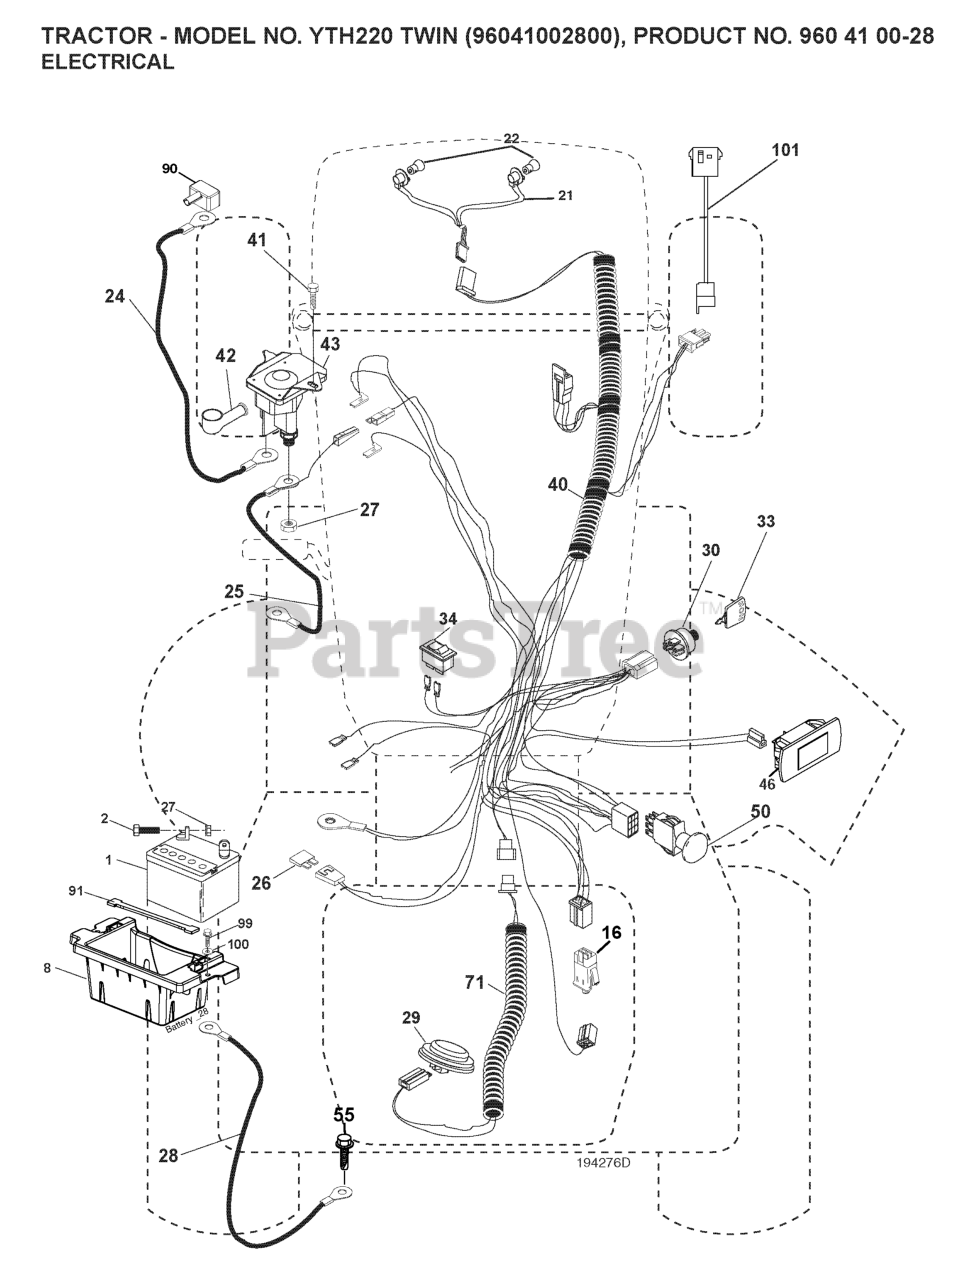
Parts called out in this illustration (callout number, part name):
1	BATTERY 12V .35 AMP
2	BOLT.HEX.1/4.X.3/4.DICHROMATE
8	BOX.BATTERY.MOUNT.FRONT.LT
16	SWITCH INTERLOOK PUSH-IN
21	HARNESS ASSY LIGHT
24	CABLE.BATT.POS.WIRE.TG.DA SOL
25	CABLE.START.RED.17.5".
26	FUSE 20AMP
27	NUT
28	CABLE GROUND 6 GA 21" 90T BLK
29	SWITCH.SEAT.DELTA.OPC.
30	SWITCH.IGN.DELTA.W.LGH.ROS
33	KEY MLD GEN DELTA
40	HARNESS.IGN.DASH.HUQ/P
41	SCREW
42	TERMINAL COVER
43	SOLENOID.W/BRASS.PLUNGER
46	RP.GUAGE.SRVCMNDR.HRMTR.
50	RP.PTO.SWITCH.8 TERMINAL.BLACK
55	SCREW 5/16"
71	HARNESS-CHASSIS SUB
90	COVER.TERMINAL.BATTERY
91	STRAP.BATTERY.MOUNT.FRONT(2 2)
99	SCREW HEXWSHR 1/4-20X3/4
101	PIGTAIL.MATNLK.NEW.HAR
